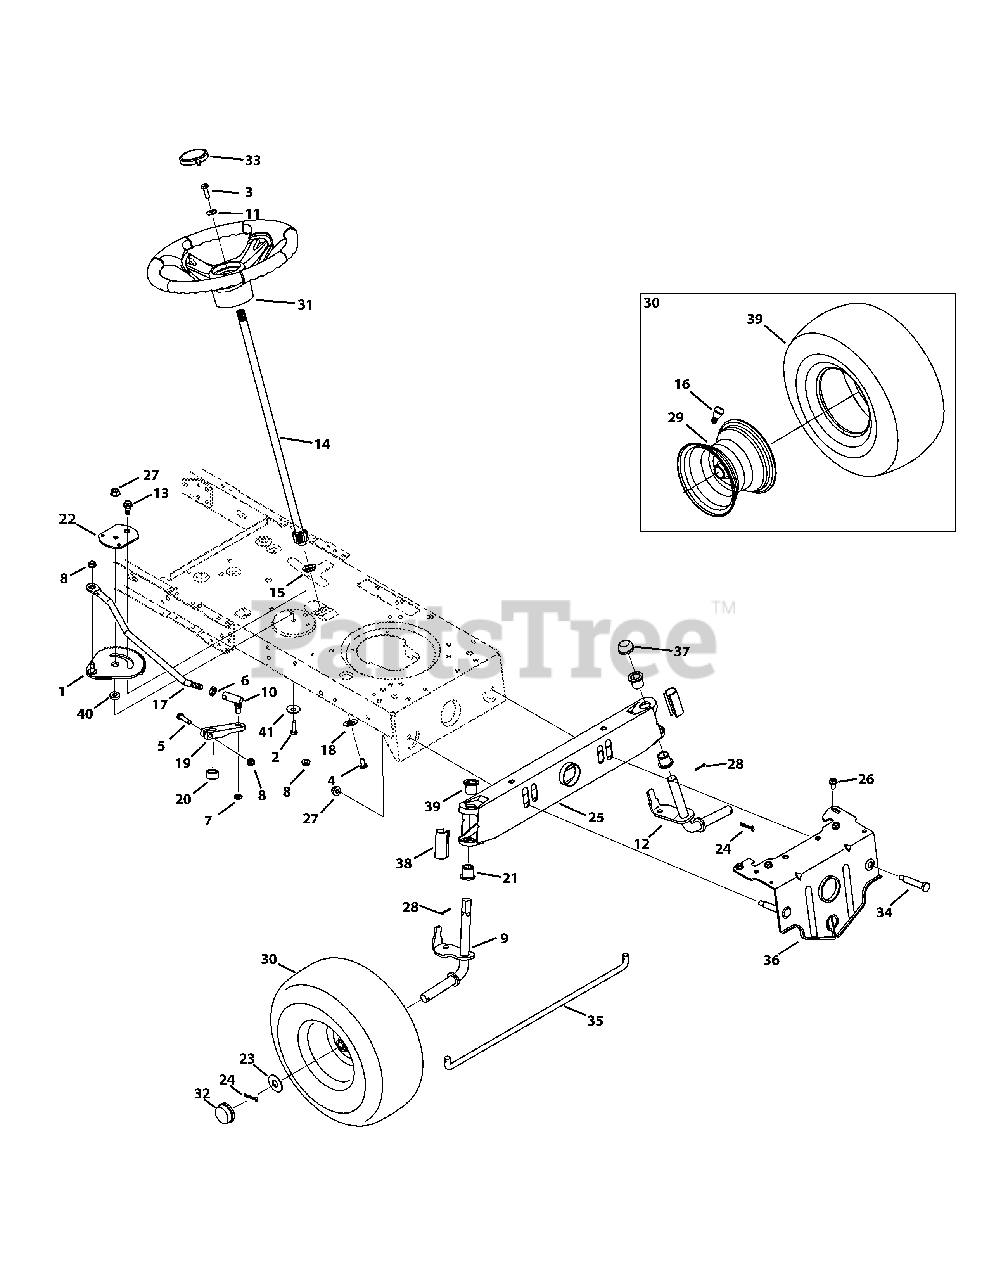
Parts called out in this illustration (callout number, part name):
1	Front Steering Gear Assembly
2	Hex Screw, 3/8-16 x 1.00
3	Hex Screw, 5/16-18 x 1.00, Lock
4	Machine Screw, 5/16-18 x .750
5	Hex Screw, 5/16-18 x 1.75
6	Jam Nut, 7/16-20
7	Jamlock Nut, 3/8-24
8	Flangelock Nut, 5/16-18
9	Front RH Axle
10	Ball Joint, 7/16-20
11	Bell Washer, .340 x .872 x .060
13	Shoulder Bolt, 5/16-18 x .435 x .350
14	Steering Shaft, 5/8
15	Flange Bearing, 5/8
16	Valve, tubeless Air
17	Steering Link
18	Cap, 1.25 x .16
19	Steering Block
20	Spacer, .71 x .125 x .56
21	Flange Bearing, .760 x .941 x 1.0
22	Stabilizer Plate
23	Flat Washer, .781 x 1.590
24	Cotter Pin, 5/32 x 1.25
26	Screw, 5/16-18 x .750
27	Flangelock Nut, 3/8-16
28	Cotter Pin, .125 x .75
29	Rim, 6.0 x 4.5
30	Wheel Assembly
31	Steering Wheel
31	Steering Wheel, Softgrip
33	Cap, Troy-Bilt
34	Shoulder Bolt, 3/8-16 x .500 x 2.38
36	Pivot Bar Bracket
37	Push Cap, 3/4
38	Standard Axle Cap
39	Tire, 15 X 6 X 6 Rd Shldr
40	Spacer, .38 ID x .854 OD x .20
41	Bell Washer, .390 x 1.13 x .062
